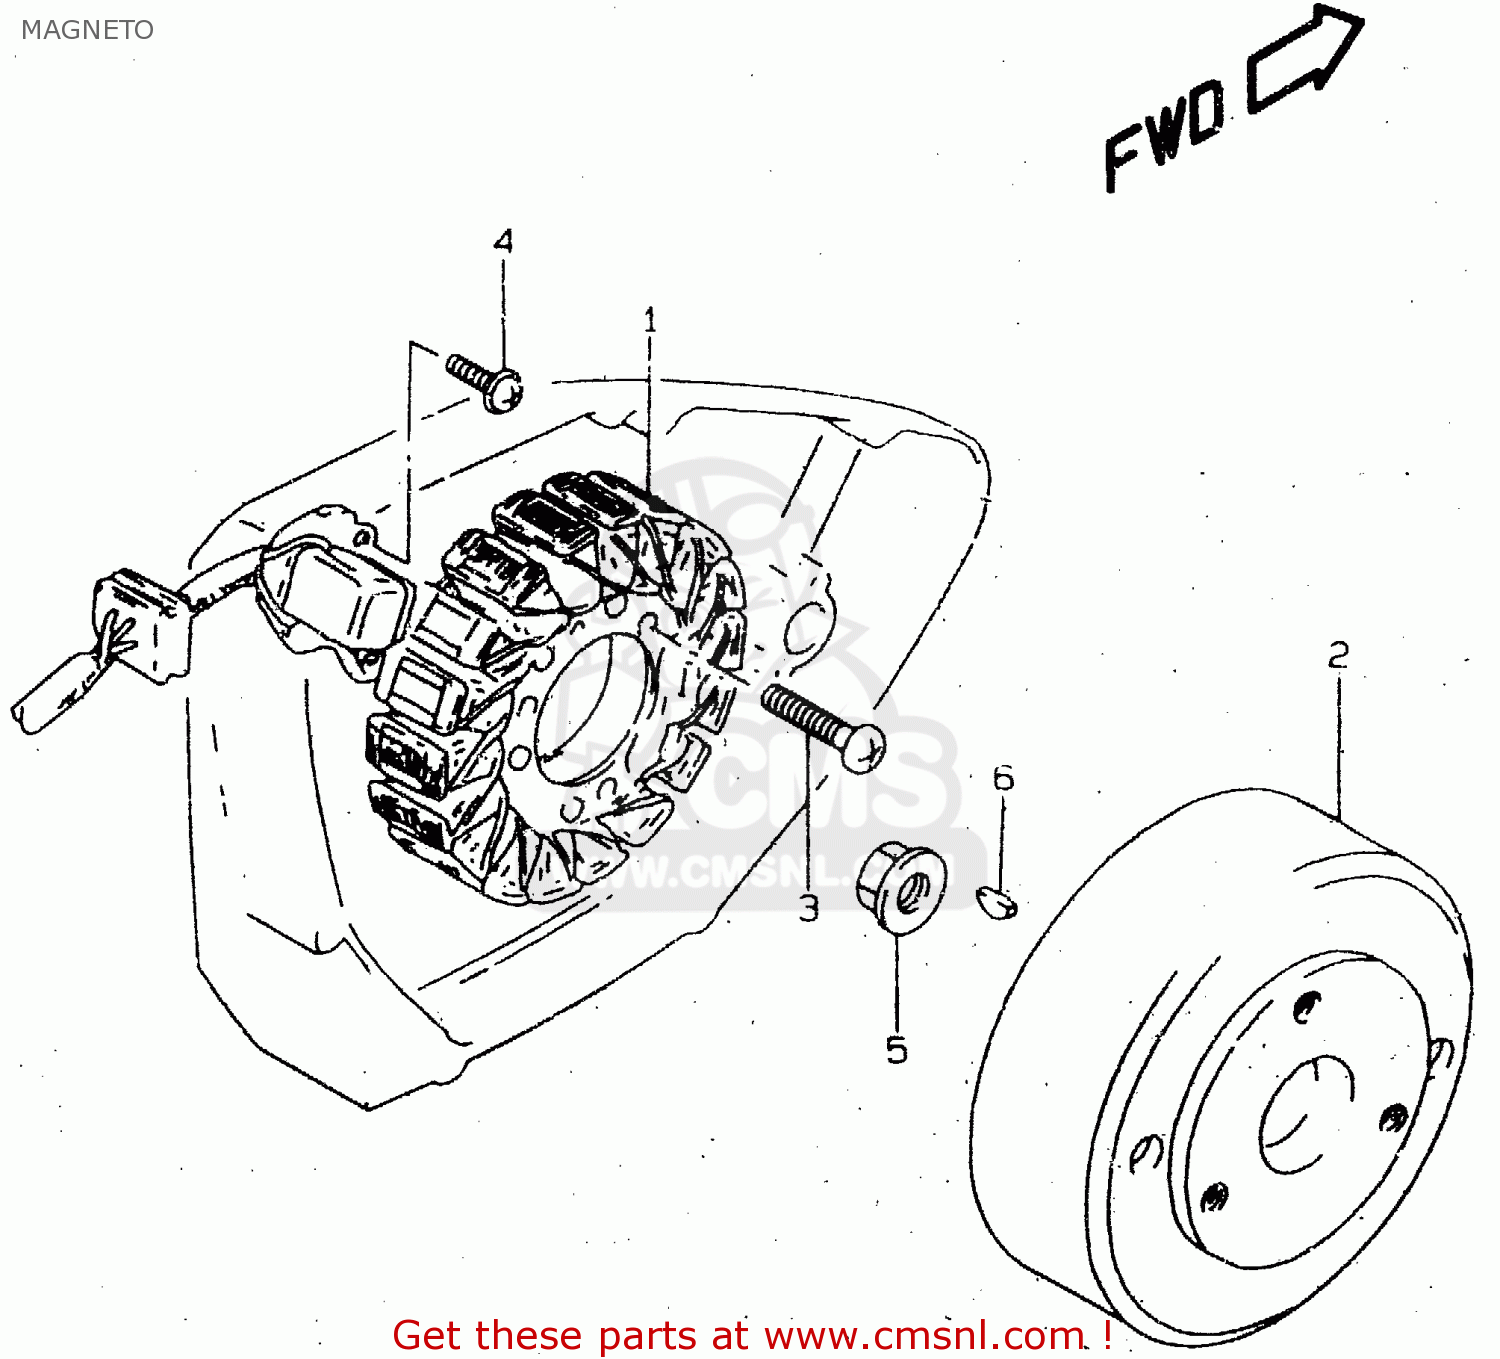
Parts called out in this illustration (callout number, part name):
1	STARTER ASSY
2	ROTOR,FLYWHEEL
3	SCREW
4	SCREW
5	NUT
6	KEY
